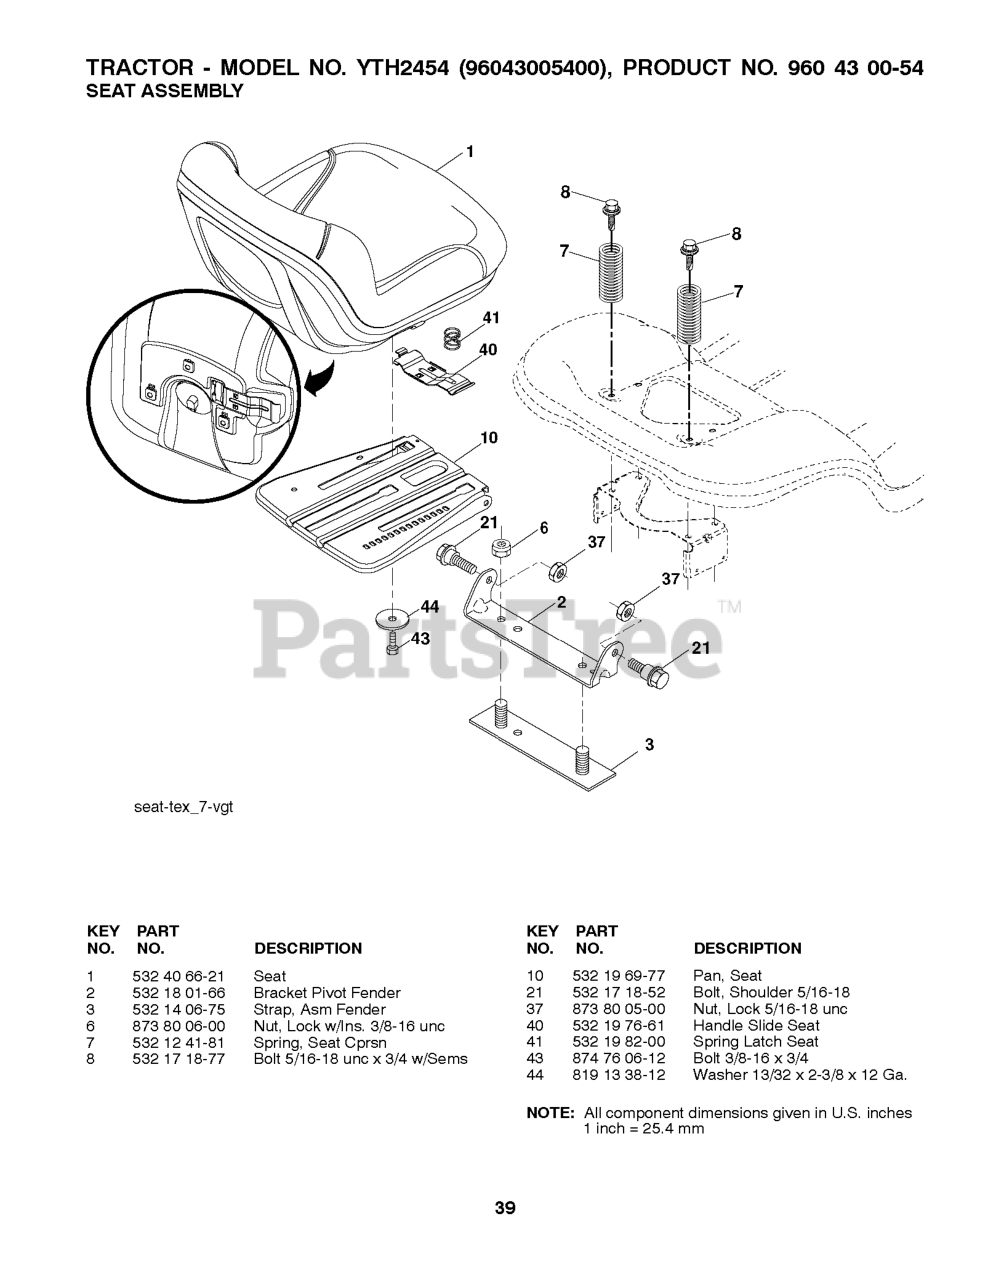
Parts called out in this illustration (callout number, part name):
1	SEAT - GREY
2	BRKT.PIVOT.FENDER
3	STRAP
6	NUT
7	SPRING COMPRESSION
8	BOLT.5/16-18UNCX3/4 W/SEMS.BLK
10	PAN.ASM.SEAT.3PT
21	BOLT.SHOULDER.5/16-18
37	NUT.71038.31-18.HEX.NYLOCK
40	HANDLE.SLIDE.SEAT.TEX.BLACK
41	SPRING.LATCH.SEAT.TEX
44	WASHER 13/32 X 2-3/8 X 12GA
